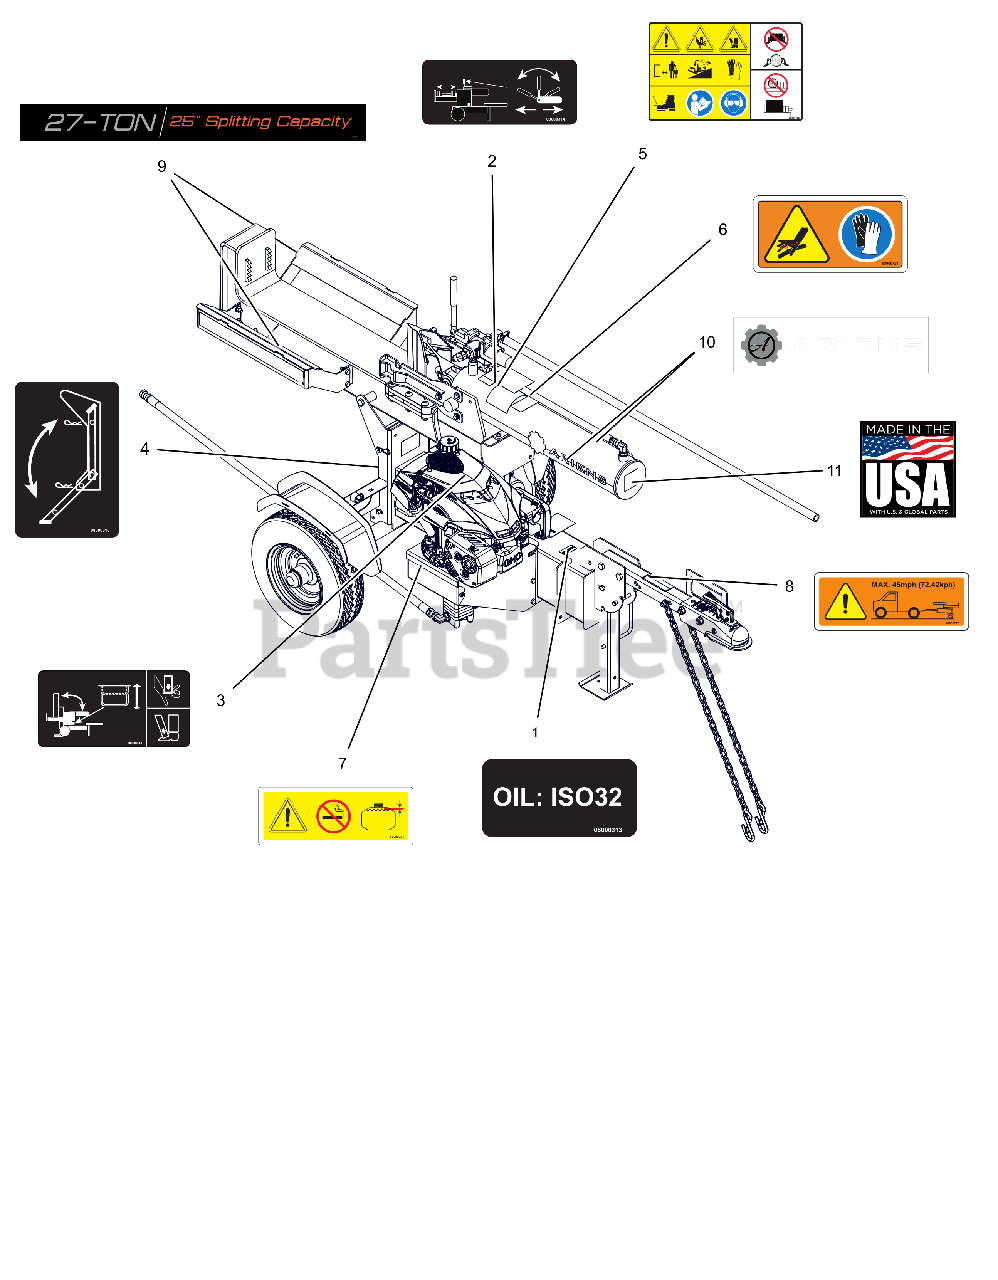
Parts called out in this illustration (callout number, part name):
1	DECAL, LOG SPLITTER-HYD OIL
2	DECAL, LOG SPLITTER-RAM OP
3	DECAL, LOG SPLITTER-TILT OP
4	DECAL, LOG SPLITTER-REAR STAND
5	DECAL,DANGER LOG SPLITTER
6	DECAL,HYD WARNING
7	DECAL,FUEL WARNING
8	DECAL,TOWING
9	DECAL-CRADLE-27 TON
10	DECAL-ARIENS-CYLINDER
11	DECAL, MADE IN USA
